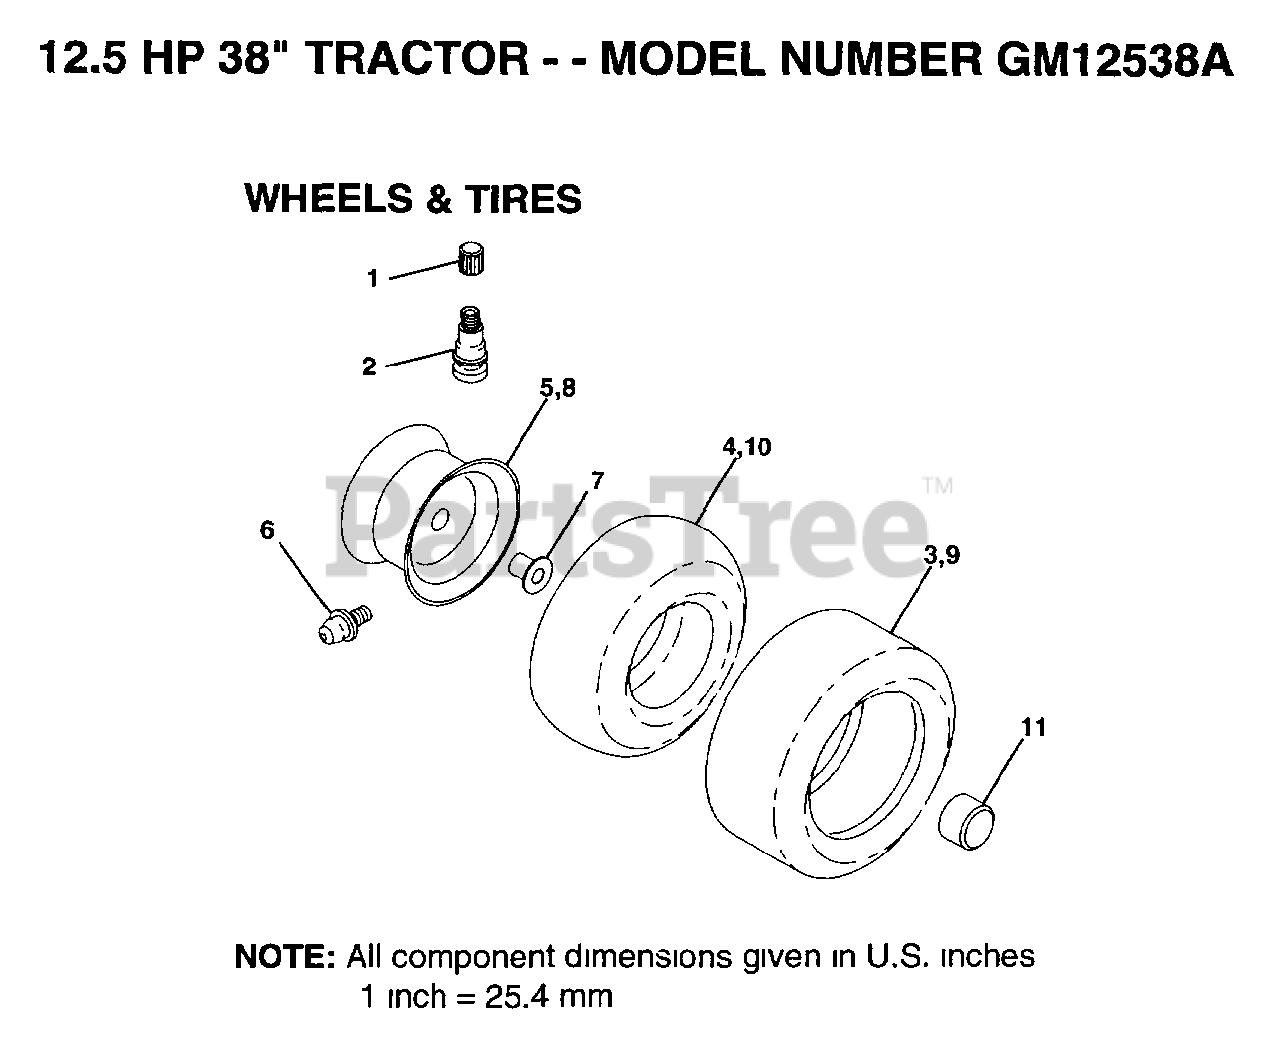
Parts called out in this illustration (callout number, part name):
1	VALVE CAP
2	VALVE STEM LT
4	TUBE.5.3/4.5/6
6	FITTING LT
7	"FLANGE, BEARING"
10	TUBE.18X9.5-8
